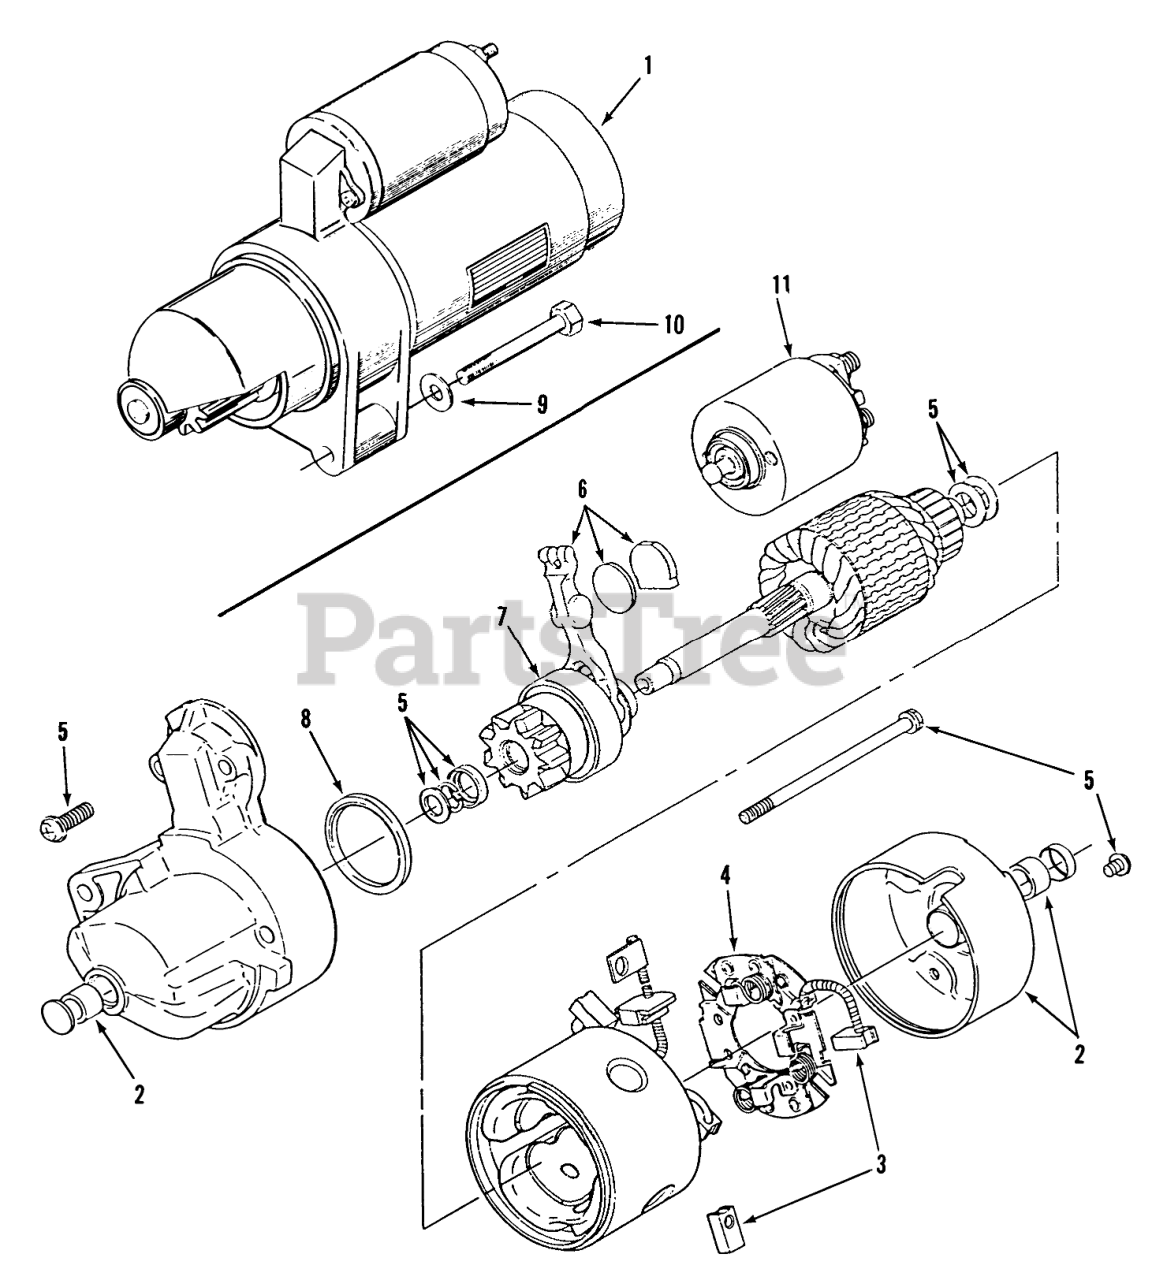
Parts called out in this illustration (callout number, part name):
1	Starter, Complete-See Components Below
2	Bushing Kit (includes Frt. Bushing and Rear Cap w/ Bushing)
3	Starter Brush Kit (includes Positive Brush (2) and Negative Brush w/ Pigtail)
4	Starter Brush Holder (includes Brush holder w/ Negative Brush)
5	Starter Hdwr. Kit (includes Solenoid Screws (2), Brush Holder Screws (2), Thru Bolts (2), Armature Shims (2), Pinion Stop Collar, and Pinion Retaining Ring)
6	Starter Shift Lever Kit (includes Shift Lever, Wear Plate and Rubber Plug)
7	Starter Clutch (includes Pinion Gear w/Clutch)
8	Dust Seal
9	Washer
10	Bolt
11	Starter Solenoid Kit (includes Solenoid, Spring and Plunger)
